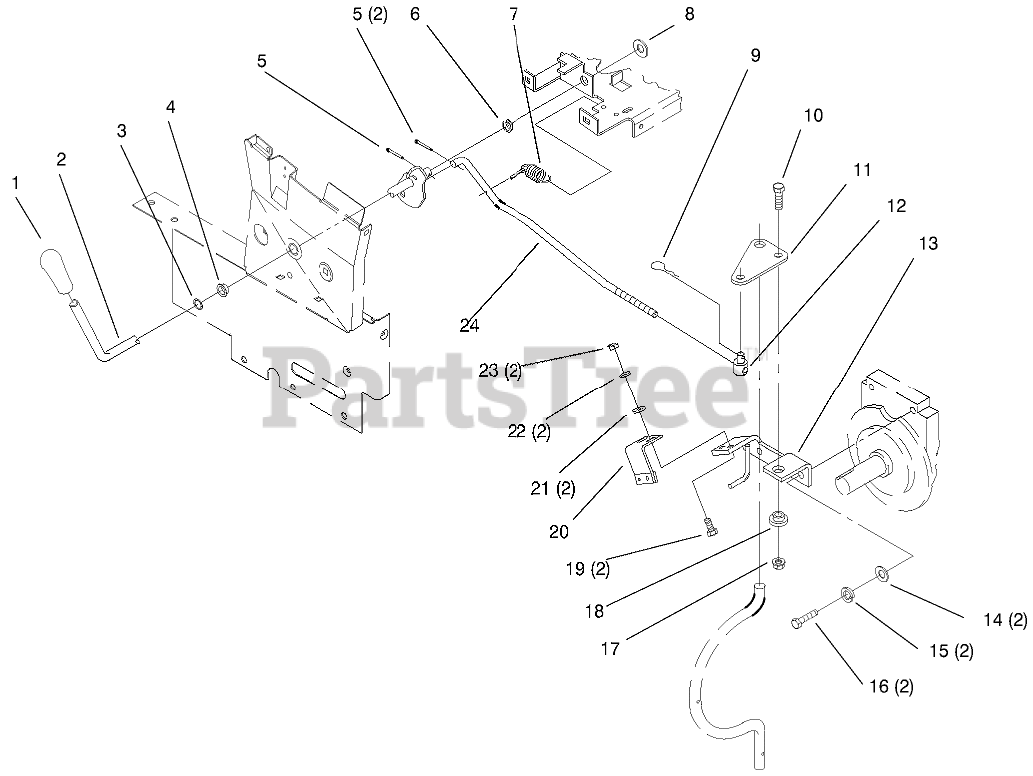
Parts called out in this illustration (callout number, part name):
2	PTO CLUTCH LEVER ASM
3	RING-EXT GRIP
4	BUSHING-NYLINER
5	PIN-COTTER
6	NYLINER BUSHING
7	SPRING
8	SHIM-WASHER
9	PIN-HAIR
10	SCREW-HH
11	PLATE
12	TRUNNION
13	ENG BRACKET WAB
14	WASHER-FLAT
15	WASHER-LOCK
16	SCREW-HH
17	NUT-LOCK, NI
18	SPACER-LIFT LINK
19	SCREW-CARR
20	ASM-Bracket
20	BRAKE ASM
21	WASHER-FLAT
22	WASHER-LOCK
23	NUT-JAM
24	ROD-PTO CLUTCH
